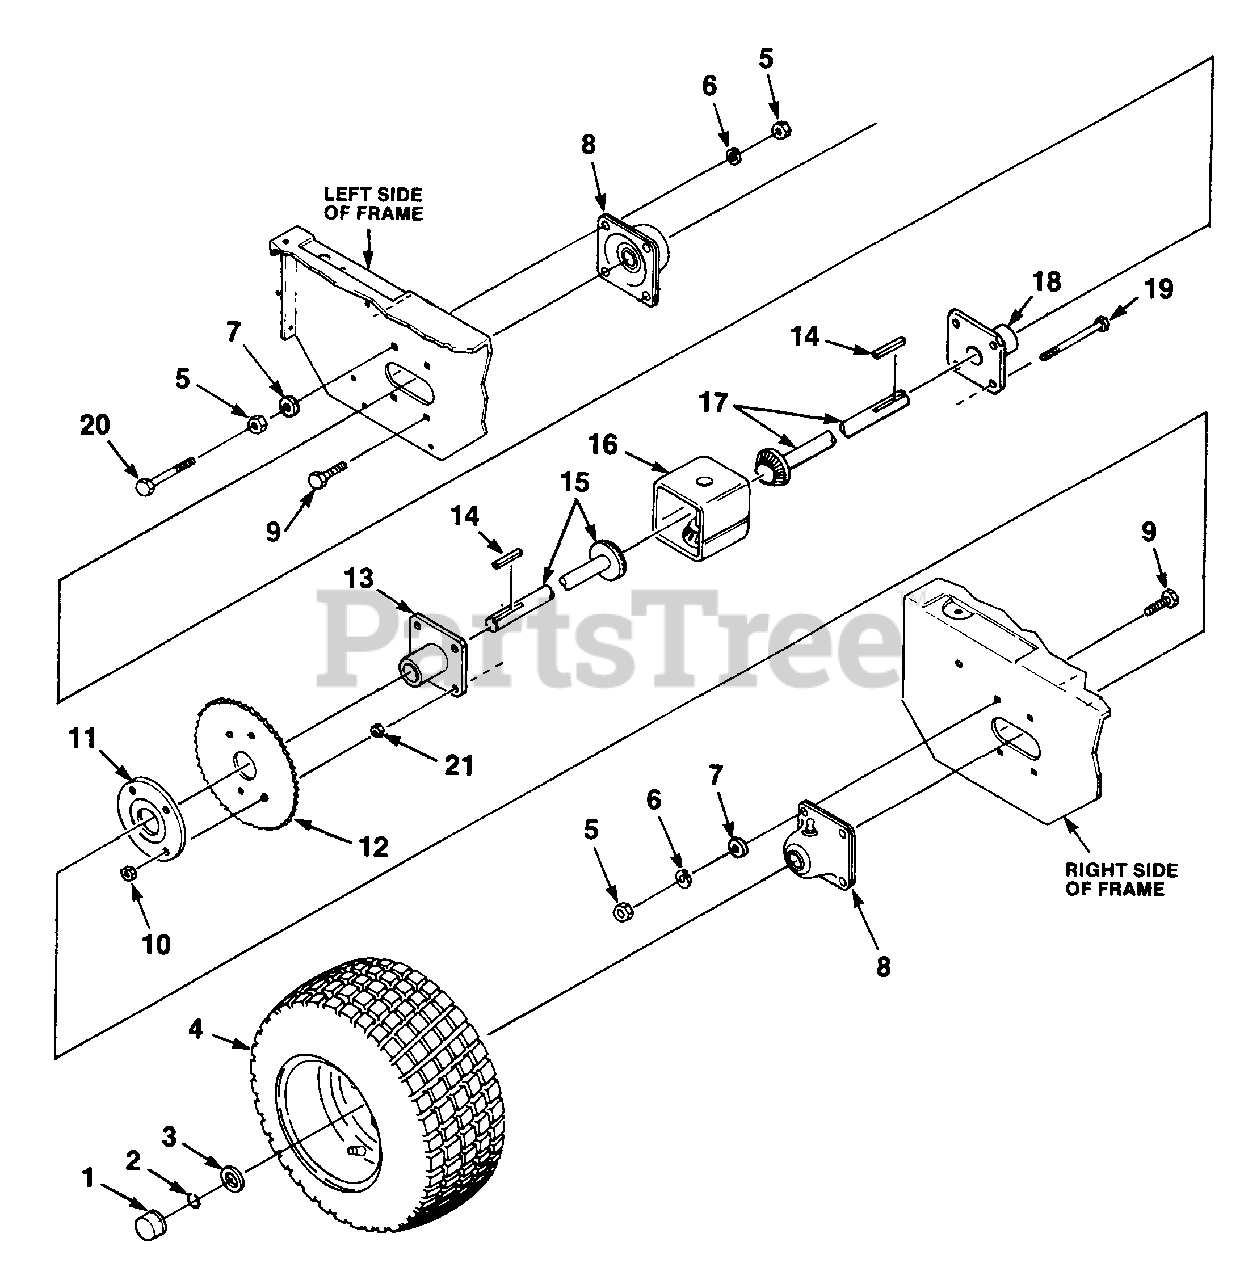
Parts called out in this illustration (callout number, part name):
2	RING- Retaining
4	WHEEL & TIRE
5	NUT- Hex 3/8-16
6	WASHER- Lock 3/8"
7	WASHER- Plain 3/8"
9	SCREW- Hex centerlock 3/8-16 x 1"
10	NUT- Hex centerlock 3/8-16
13	CAP & BEARING (R.H)
15	AXLE- R.H. w/gear
16	HOUSING & GEAR
17	AXLE- L.H. w/gear
18	CAP & BEARING (L.H.)
19	SCREW- Hex 5/16-18 x 4"
20	SCREW- 3/8-16 x 2 1/4"
21	NUT- Hex jam
